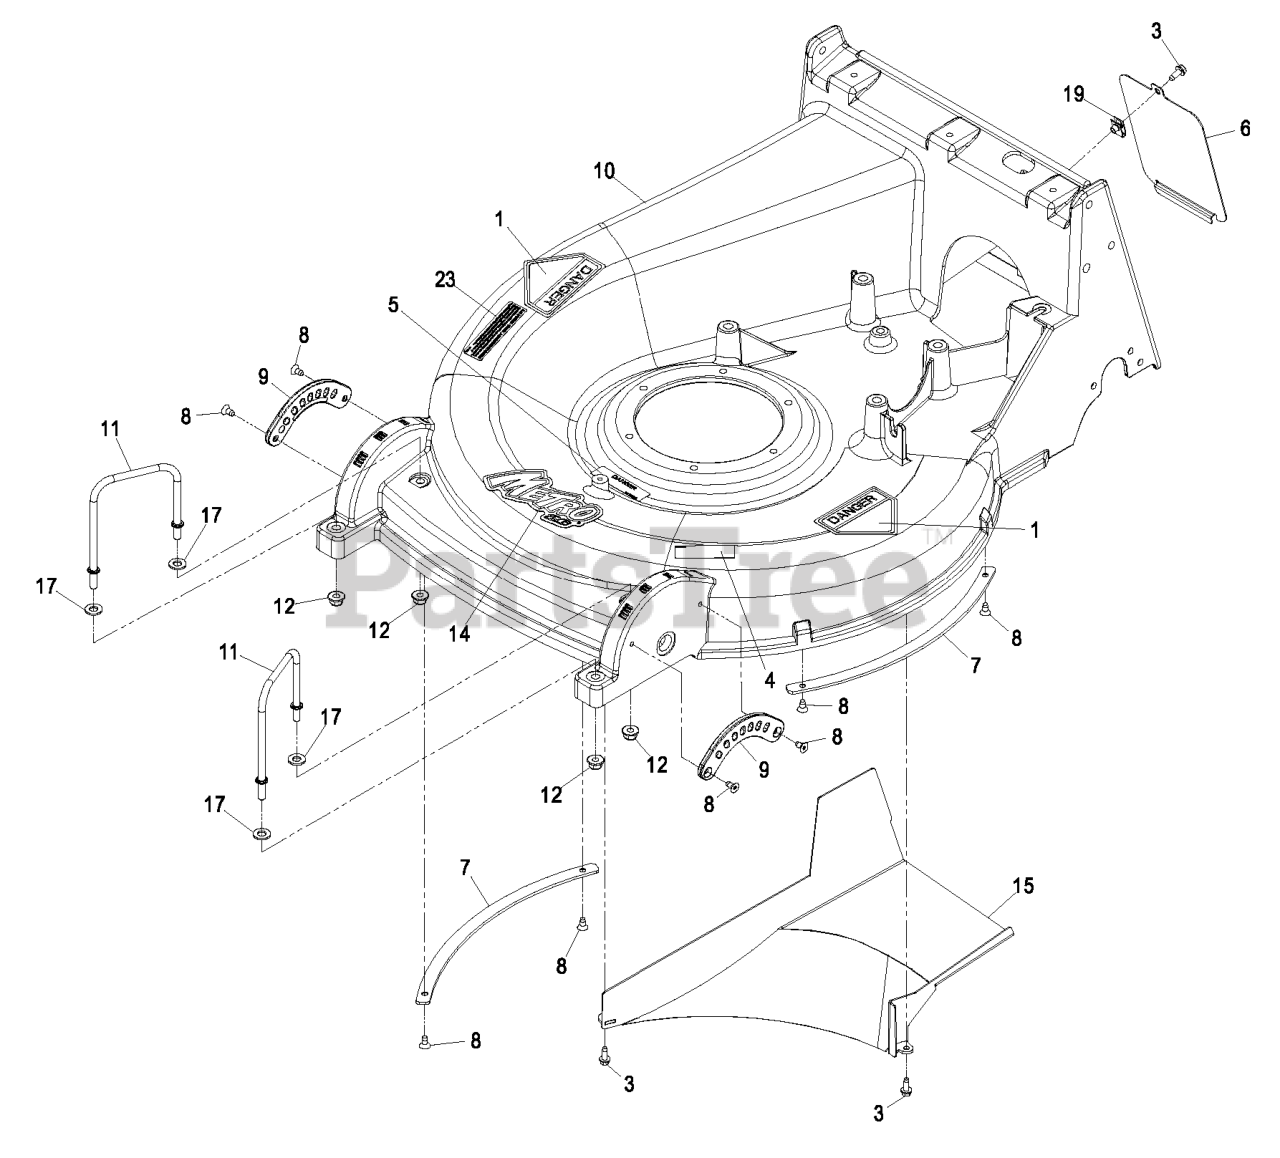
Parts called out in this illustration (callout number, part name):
1	DECAL-DANGER
3	SCREW-HWH
4	DECAL-BLADE
5	DECAL-COVER, MISSING
6	COVER-ACCESS, AXLE
7	PLATE-SKID, 10 GAGE
9	QUADRANT-FRONT
10	ASM,DECK M26 W/DECALS
12	NUT-HF, NI
14	DECAL,METRO 26
15	CHUTE ASM
17	WASHER-FLAT
19	Nut, Retainer-Panel 1/4-20
23	DECAL-ARRESTER, SPARK
